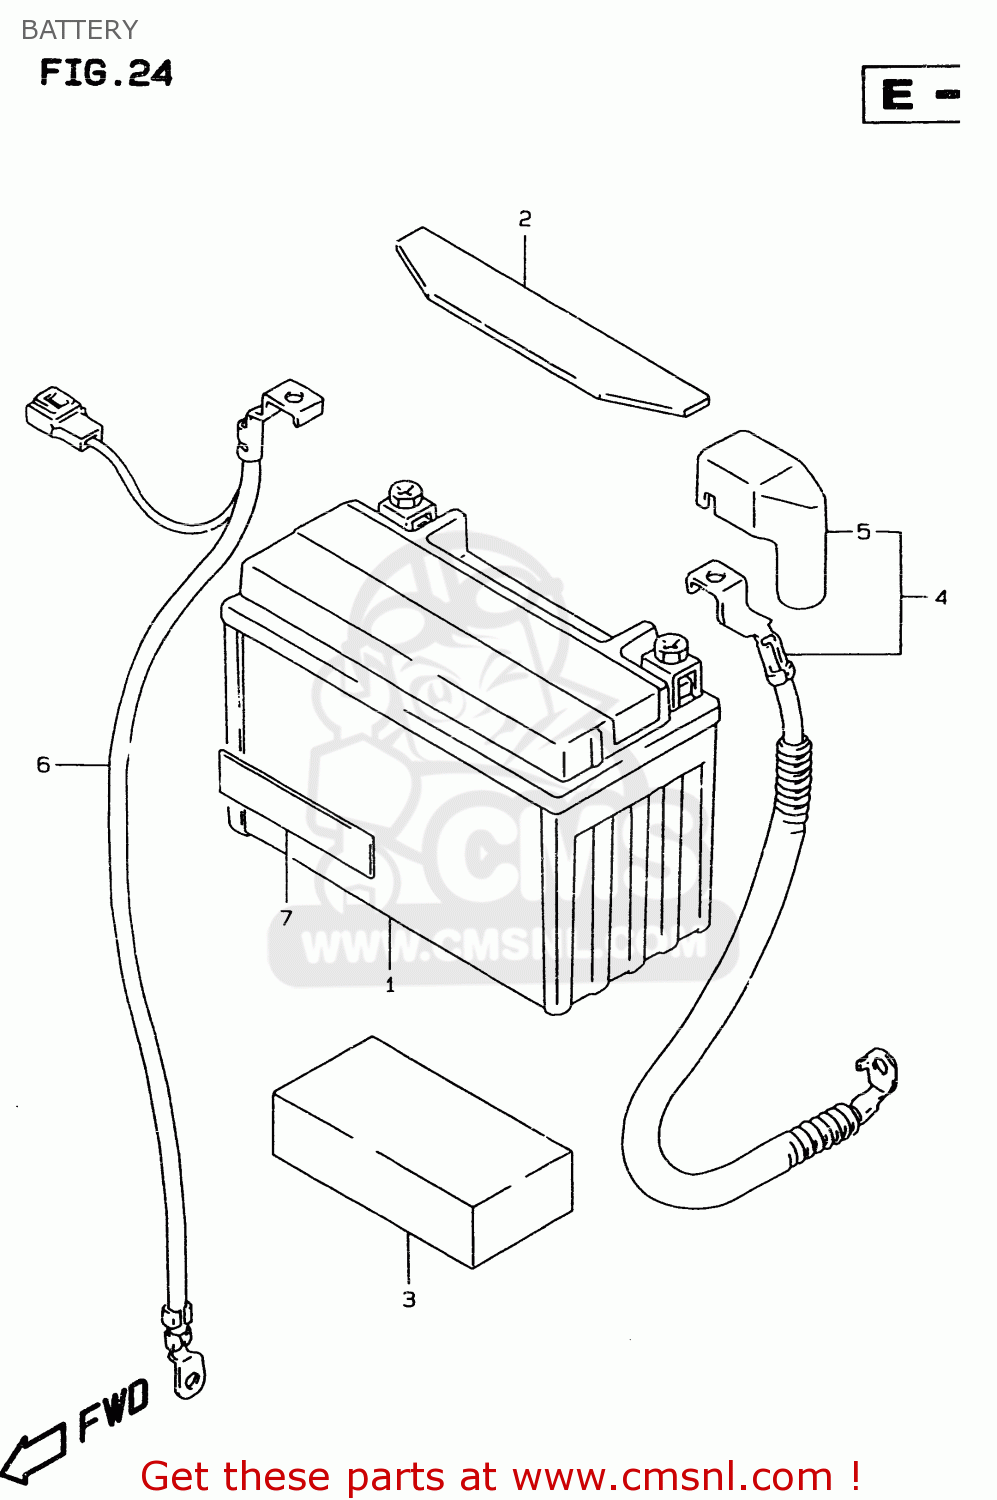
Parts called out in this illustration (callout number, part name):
1	BATTERY ASSY(YTX9-BS,12V8AH)
2	PROTECTOR,BATTERY
3	CUSHION,BATTERY
4	WIRE,BATTERY PLUS LEAD
5	CAP,BATTERY PLUS TERMINAL
6	WIRE,BATTERY MINUS
7	PROTECTOR(20X90)X1.0
